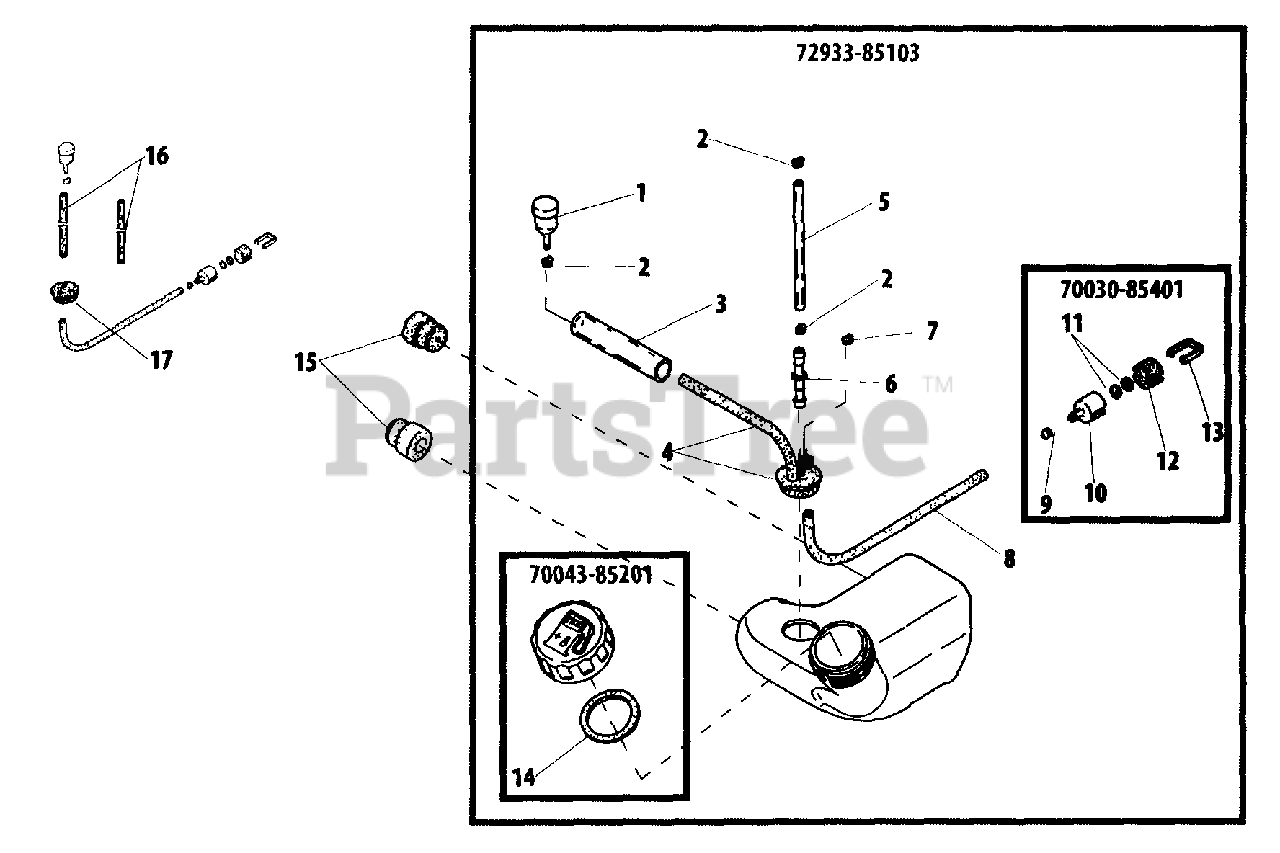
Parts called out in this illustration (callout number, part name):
1	BODY, BREATHER
2	CLIP Ø6
3	PIPE
4	GROMMET, FUEL W/VENT PIPE
5	PIPE, FUEL
6	CONNECTOR, PIPE
7	CLIP
8	PIPE, FUEL
9	CLIP Ø6
10	WEIGHT, FUEL FILTER
11	SCREEN, FUEL INLET
12	FILTER, FUEL
13	CLIP, FILTER
14	GASKET, FUEL CAP
15	CUSHION
16	TUBE
17	GROMMET
